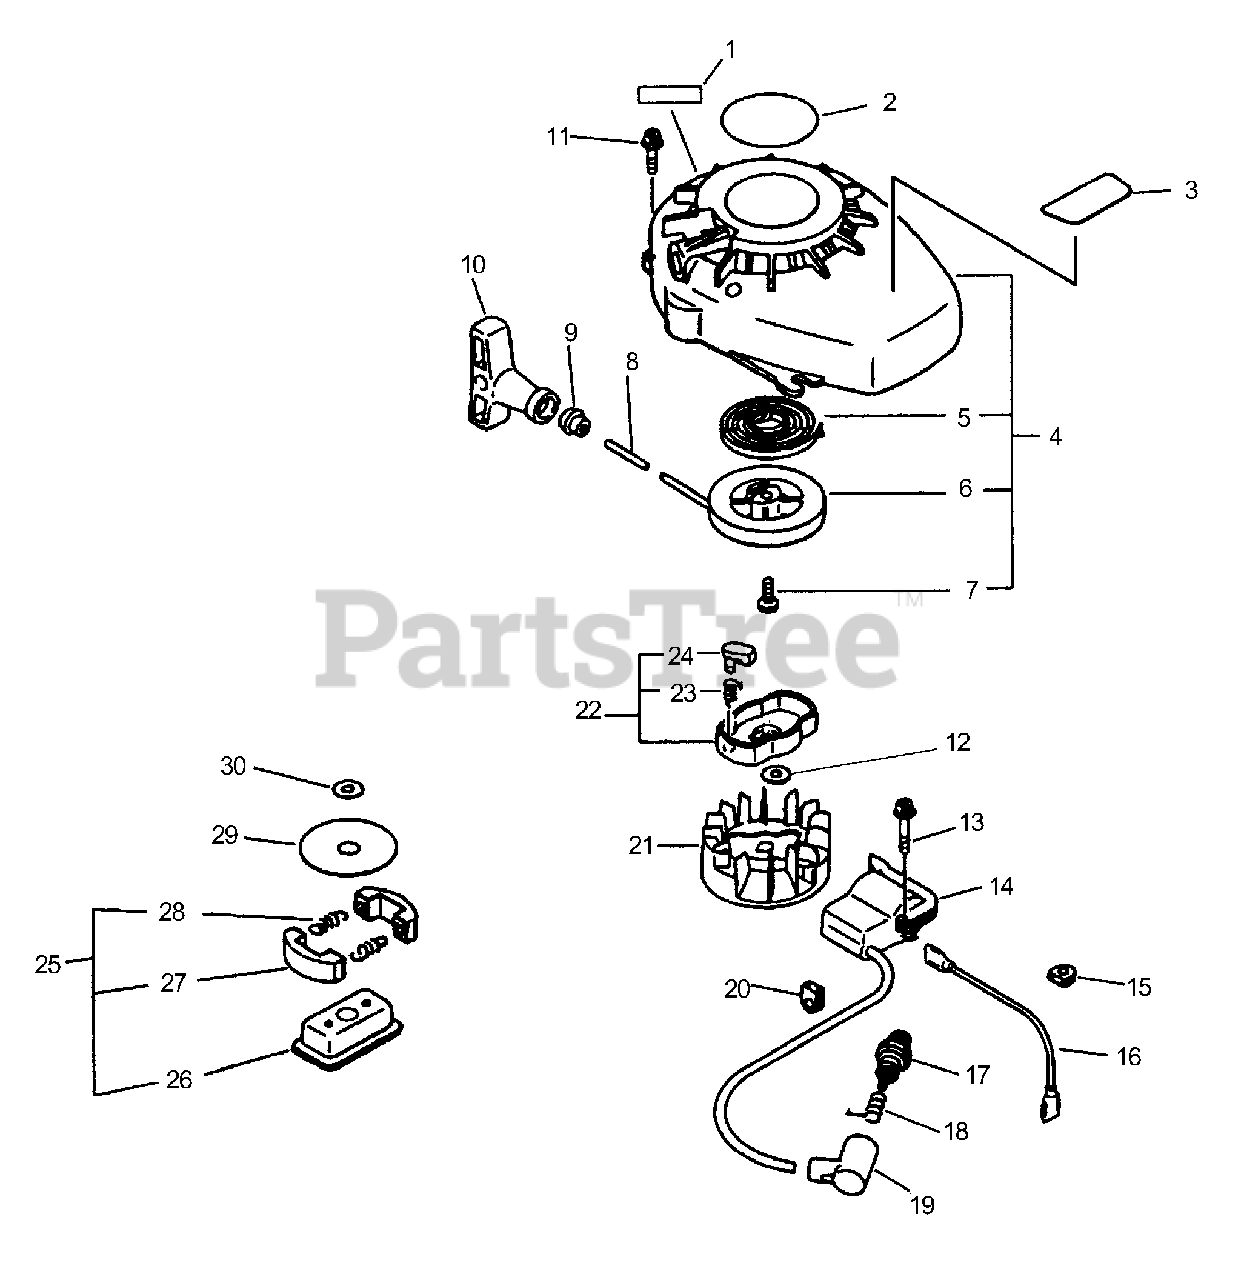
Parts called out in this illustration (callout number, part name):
1	LABEL - CAUTION
2	LABEL - MODEL
3	LABEL - CAUTION
4	STARTER ASSY
5	SPRING, REWIND
6	REEL, ROPE
8	ROPE, STARTER - 3X890
9	GUIDE, ROPE
10	GRIP, STARTER
11	SCREW - 4X16
12	LOCKWASHER - 8
13	SCREW - 4X22
14	COIL, IGNITION
16	LEAD - IGNITION
17	SPARK PLUG -- BPM-7Y
17	SPARK PLUG -- BPMR-7A
18	TERMINAL, SPARK PLUG CAP
19	CAP, SPARK PLUG
21	FLYWHEEL
22	STARTER PAWL ASSY
23	SPRING, RETURN
24	PAWL, STARTER - BLACK
25	CLUTCH ASSY
26	HUB, CLUTCH
27	SHOE, CLUTCH
28	SPRING, CLUTCH
29	PLATE, CLUTCH
30	WASHER, CLUTCH
